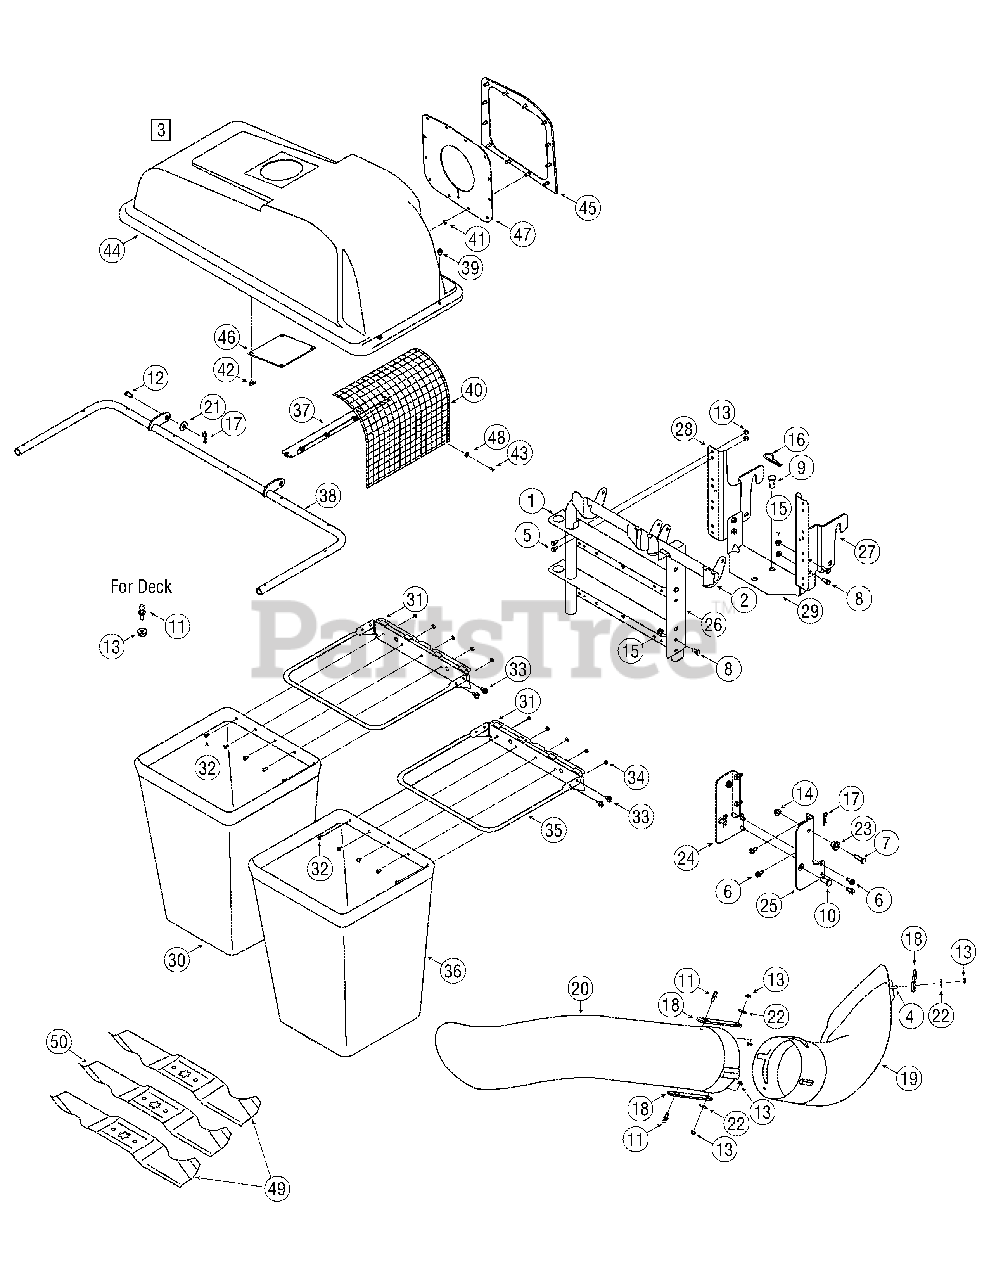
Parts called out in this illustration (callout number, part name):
1	Support Bracket: Bagger
2	Support Tube Assembly
3	Grass catcher Cover Assy
4	Screw 1/4-20 x 1"
5	Hex Head Screw 1/4-20 x .62
6	Self-Tap. Screw 5/16-18 x .75
7	Hex Hd. Screw, 3/8-16 x 1.25
8	Hex Hd. Screw, 5/16-18 x .75
9	Clevis Pin, .62 Dia.
10	Clevis Pin, .50 x 1.18
11	Grass Catcher Pin 1/4-20
12	Clevis Pin, 3/8 x .75
13	Hex Flange Lock Nut, 1/4-20
14	Hex Flange Lock Nut, 3/8-16
15	Hex Flg. Lock Nut, 5/16-18
16	Hairpin Clip
17	Click Pin
18	Chute Strap
19	Discharge Chute 38"/42" Deck
19	Discharge Chute 46" Deck
20	Chute Tube 38"/42" Deck
20	Chute Tube 46" Deck
21	Bell Washer
22	Flat Washer
23	Shoulder Spacer
24	Mounting Bracket, LH
25	Mounting Bracket, RH
26	Mounting Bracket
27	Mounting Bracket RH
28	Mounting Bracket LH
29	Bracket: Cross Support
31	Bag Hanger Bracket
32	Machine Screw, , #10-24 x .5
33	Self-tap. Scr., 5/16-18 x .625
34	Hex Sems Nut, #10-24
35	Grass Bag Frame
36	Grass Catcher Bag
37	Screen Mounting Bracket
38	Hinge Assembly
39	Self-Tap. Screw 1/4-20 x .625
40	Grass catcher Sceen
41	Push Nut, .25 x .50
42	Zip Twist Fastener
43	Pop Rivet, 3/16 x .450
44	Double Grassbag Cover
45	Grassbag Hopper Seal
46	Plastic Plate, 1/8 x 5.6
47	Grassbag Hopper Seal
48	Flat Washer, .194 x .62 x .063
49	2-in-1 Blade 16.28"
50	2-in-1 Blade 14.88"
